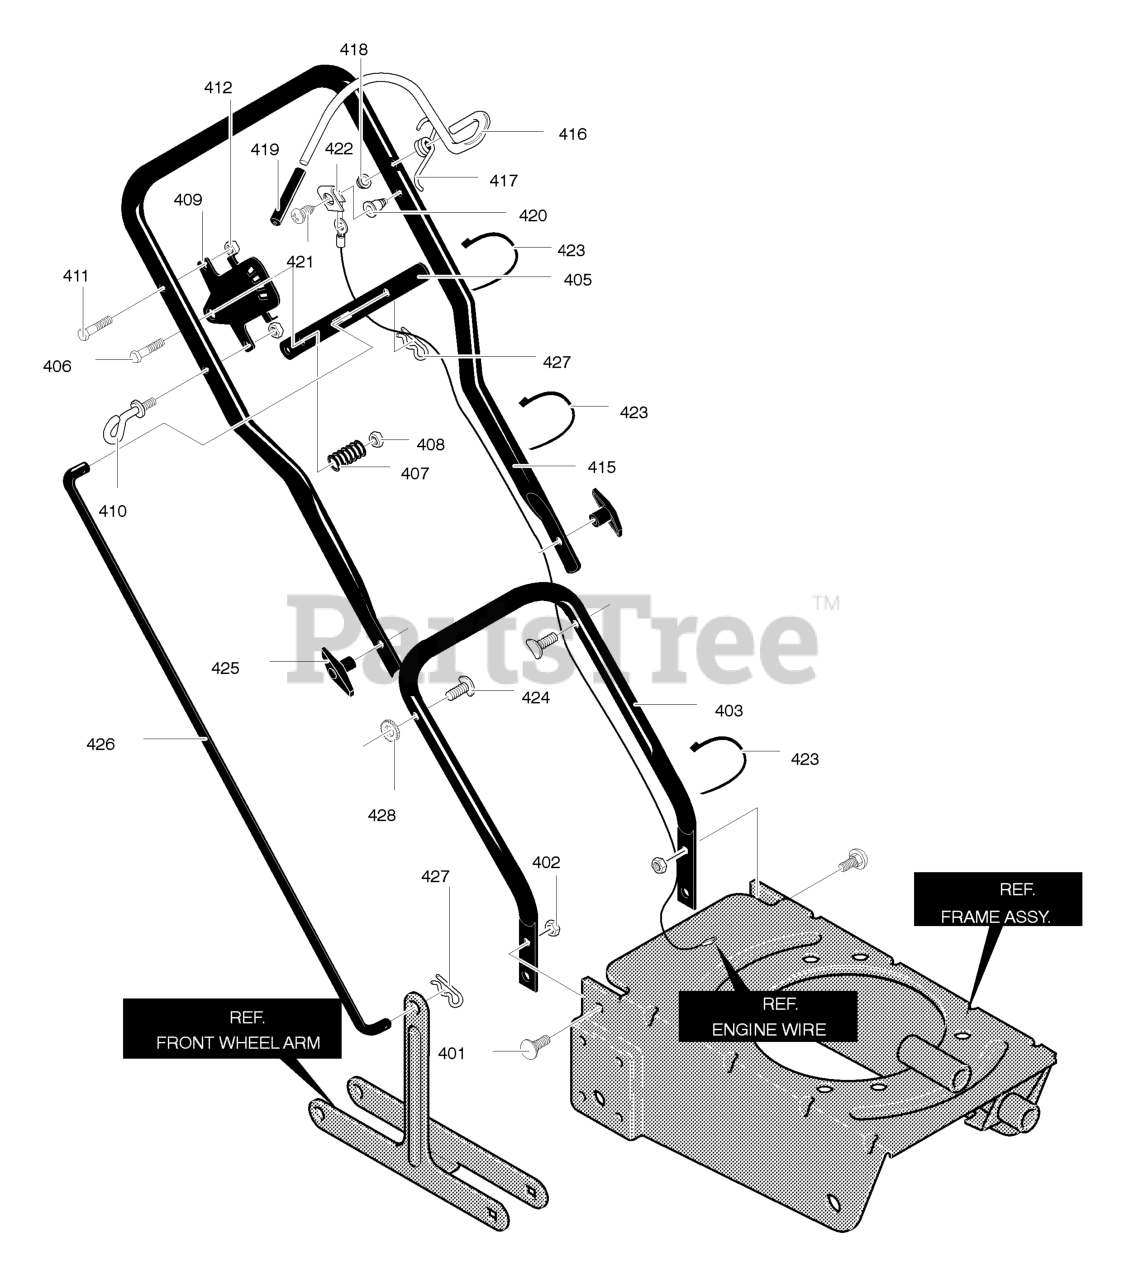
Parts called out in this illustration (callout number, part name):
401	Bolt, 5/16-18x.75
402	Nut, 5/16-18
403	Lower Handle
405	Handle, Depth
407	Spring, Compression
408	Nut, 5/16-18
409	Brkt, Adj. Quadrant
410	Rope Guide
411	Screw, 1/4-20x1.25
412	Nut, 1/4-20
415	Upper Handle
416	Bail, Operator Control
417	Torsion Spring
418	Nut, Push On
419	Grip, Operator Control
420	Insulator, Oper Control
421	Screw, #6x.50
422	Clip, Grounding
423	Cable Tie
424	Bolt, 5/16-18x.75
425	Wing Knob 5/16-18
426	Rod, Control
427	Hair Pin
428	Washer, Exlk.
